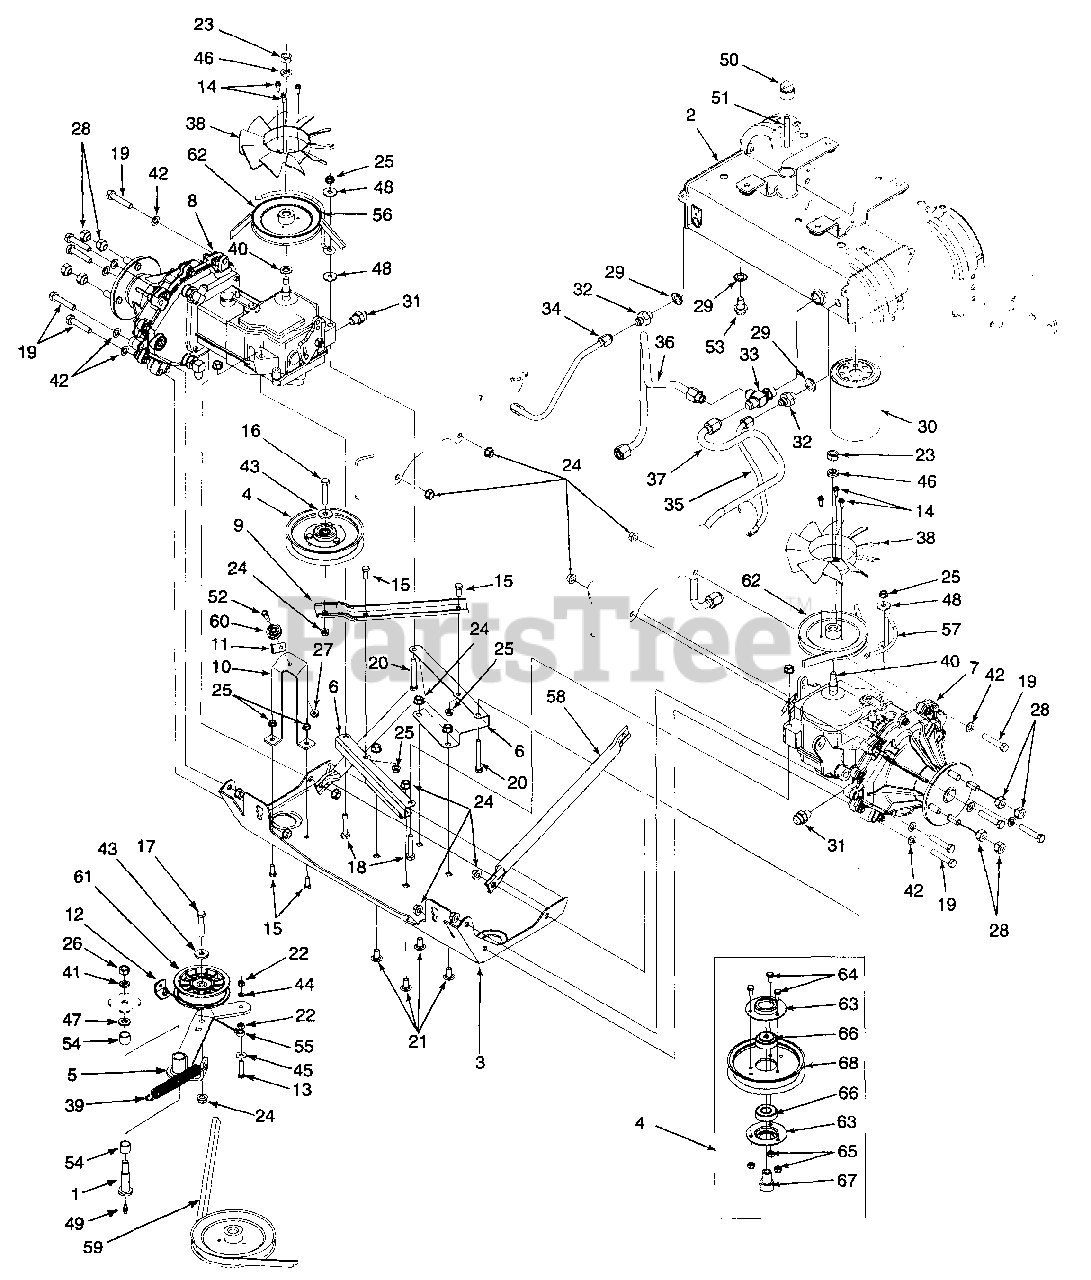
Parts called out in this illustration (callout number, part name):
1	Shoulder Bolt, Special
8	Transmission Ass'y LH
11	Bracket, Cable Retainer
12	Bracket, Cable Mtg
13	Screw, Hex Cap 1/4-28 x 1.25 GR5
14	Screw, Hex Wash Hd Tapp #12-24 x .62
15	Screw, Hex Cap 5/16-18 x .75 GR5
16	Screw, Hex Cap 3/8-16 x 2-1/4 GR5
17	Screw, Hex Cap 3/8-16 x 1-3/4 GR5
18	Screw, Hex Cap 5/16-18 x 2.0 GR5
19	Screw, Hex Cap 3/8-16 x 2.0 GR5
20	Screw, Hex Cap 5/16-18 x 2.50 GR5
21	Bolt, Carriage, 3/8-16 x .75
22	Nut, Hex, 1/4-28
23	Nut, Hex, 1/2-20
24	Nut, Hex Flange Lock, 3/8-16
25	Nut, Hex Flange Lock, 5/16-18 GR5
26	Nut, Hex, 7/16-14
27	Nut, Hex Lock, 1/4-28
28	Nut, Lug, 7/16-14
29	Seal, Drain Plug
30	Filter Element, Oil
31	Fitting, Connector, 1/2 x 3/8
32	Fitting, Connector
33	Fitting, Tee, 1/2 x 1/2 x 3/4
34	Tube, Inlet LH
35	Tube, Inlet RH
36	Tube, Outlet LH
37	Tube, Outlet RH
38	Fan, 10 Blade
39	Spring, Extension
40	Wire Ring
41	Washer, Lock, 7/16
42	Washer, Flat, .406 x .75 x .06
43	Washer, Flat, .385 x 1.0 x .135
44	Washer, Lock, 1/4 ID
45	Washer, Flat, .283 x .75 x .030
46	Washer, Lock, 1/2
47	Washer, Flat, .469 x .875 x .105
48	Washer, Flat, 5/16 x .934 x .100
49	Fitting, Grease
50	Plug, Pipe, w/ Vent 3/4 NPTF
51	Tube, Dipstick
52	Bolt, Shoulder, 1/4-28: .375
53	Plug, Oil Drain
54	Bearing, Sleeve, .628 x .75 x .625
55	Cable, Declutching
56	Rod, Belt Retaining RH
57	Rod, Belt Retaining LH
60	Cable Roller
61	Pulley, Flat Idler 3.5 in
62	Pulley, Transmission
63	Cup, Bearing
64	Screw, Hex Cap, 1/4-20 x .62 GR5
65	Nut, Hex Insert Lock, 1/4-20
66	Bearing, Ball
67	Spacer, Idler
68	Pulley, Idler 5.0 in.
